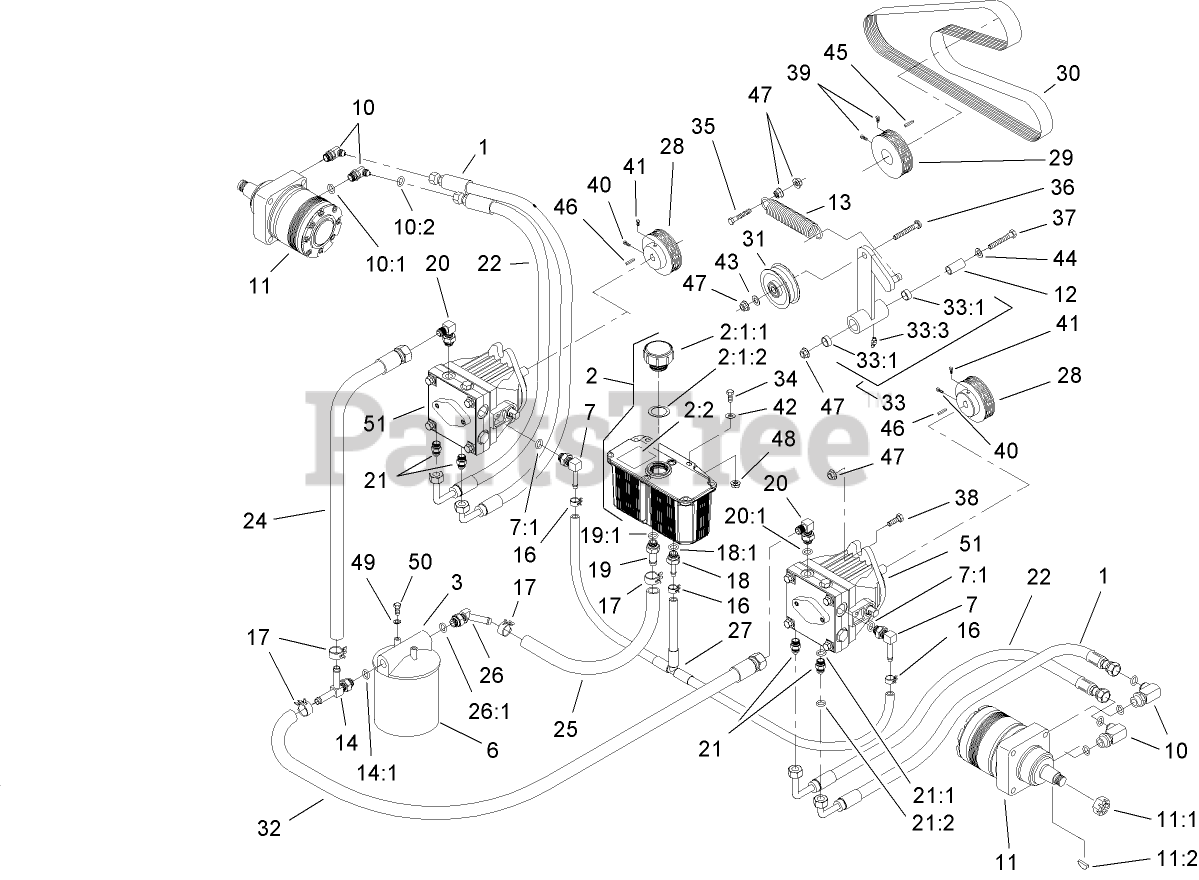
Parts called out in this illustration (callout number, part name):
1	HYD Hose ASM
2	HYD Reservoir ASM
2:1	Reservoir-HYD
2:1:1	CAP-RESERVOIR, HYD
2:1:2	GASKET-CAP
2:2	DECAL-TANK, HYD
3	HEAD-FILTER
6	FILTER-OIL, HYD (WINTER)
6	FILTER-OIL, HYD
7	ELBOW-90 DEG
7:1	O-RING
10	FITTING-90 DEG
10:1	O-RING
10:2	O-Ring
11	MOTOR-WHEEL
11:1	NUT-HH
11:2	KEY-WOODRUFF
12	BUSHING-PIVOT, IDLER
13	Spring-Extension
14	ADAPTER-RUN, TEE
14:1	O-RING
16	Clamp-Hose
17	Clamp-Hose
18	Adapter-Straight
18:1	O-RING
19	ADAPTER-STRAIGHT
19:1	O-RING
20	FITTING-ELBOW, 90 DEG
20:1	O-Ring
21	FITTING-STRAIGHT
21:1	O-RING
21:2	O-Ring
22	Hose-Lower
24	HYD Hose ASM
25	Hose-HYD
26	FITTING-BARBED, 45 DEG
26:1	O-RING
27	HYD Hose ASM
28	SHEAVE
29	SHEAVE
30	BELT-V
31	SHEAVE-IDLER
32	HYD Hose ASM
33	BEARING ARM ASM
33:1	SLEEVE-BEARING
33:3	FITTING-GREASE, 90 DEG
34	SCREW-HH
35	SCREW-HH
36	SCREW-HH
37	SCREW-HH
38	SCREW-HH
39	SCREW-SET
40	SCREW-SET
41	SCREW-SET
42	WASHER-FLAT
43	WASHER-FLAT
44	WASHER-FLAT
45	KEY-SQUARE
47	NUT-HHF, WHIZ
48	NUT-HF
49	WASHER-LOCK
50	SCREW-HH
51	PUMP-HYD
